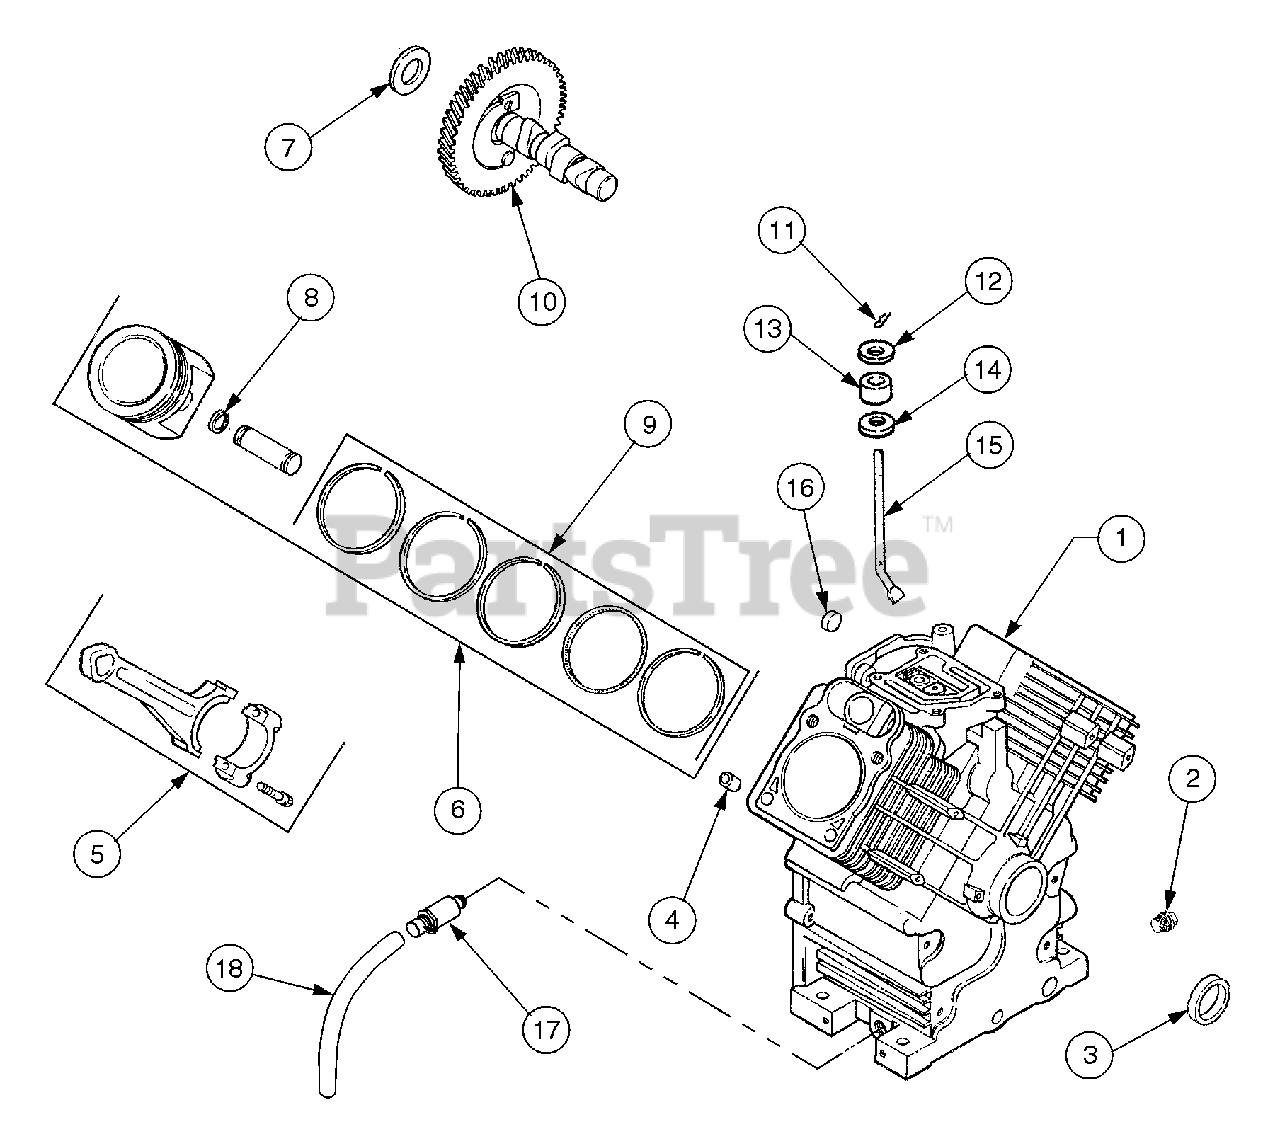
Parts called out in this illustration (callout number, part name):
1	Cylinder Block, (Miniblock) (6mm)
2	Plug, Hex Hd, 3/8
3	Seal, Front Oil
4	Pin, Locating Dowel
5	Rod, Connecting, Std
6	Piston w/Ring Set, Std
7	Shim, Camshaft, .0320 (Red)
8	Retainer, Piston Pin
9	Ring Set, Std
10	Camshaft Assembly
11	Pin, Hitch (6mm)
12	Washer, Plain (6mm)
13	Seal, Gov. Cross Shaft (6mm)
14	Washer (Bottom) (6mm)
15	Shaft, Gov. Cross (6mm)
16	Plug, Cup
17	Drain, Oil
18	Hose, Oil Drain
